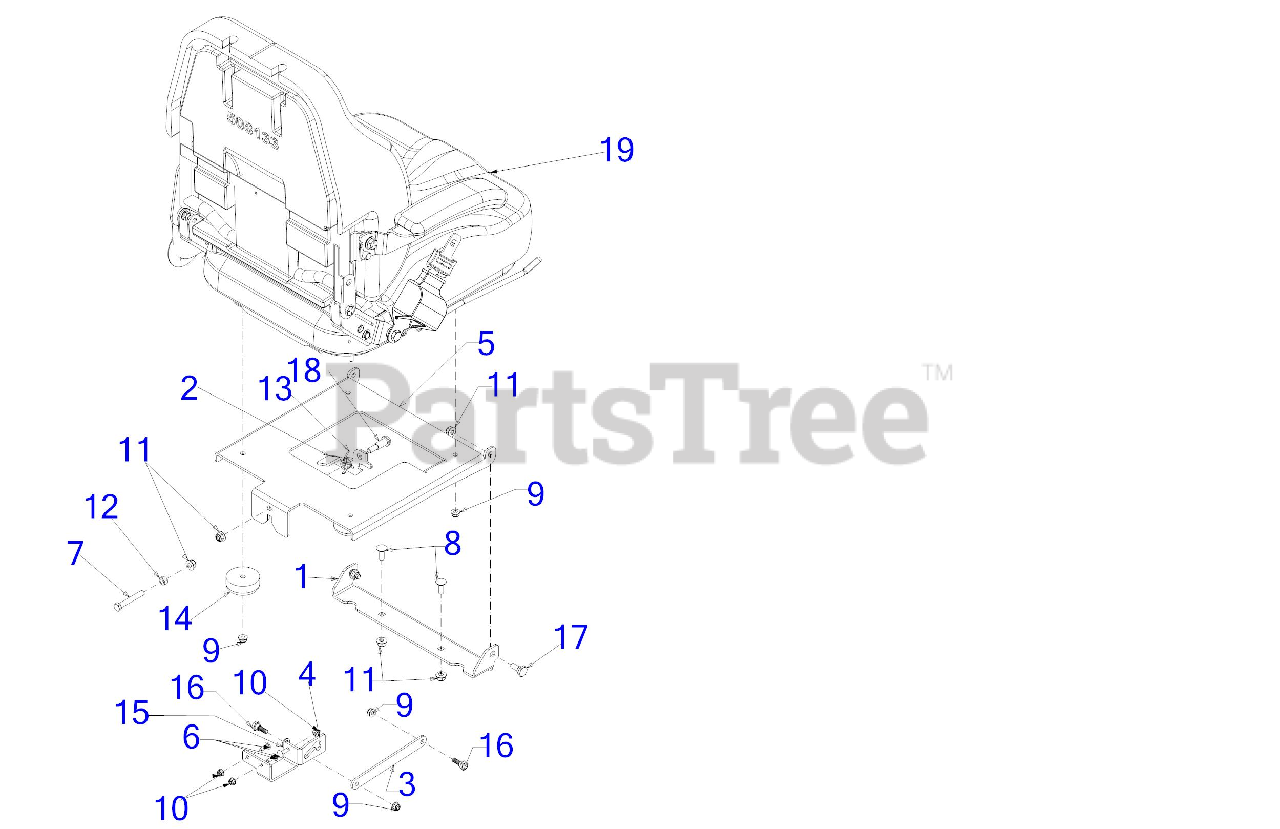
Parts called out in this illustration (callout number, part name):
3	SEAT LOCKOUT BRACKET
4	SEAT LOCKOUT MOUNT
6	SCREW 1/4-20 x .75 GR5
7	HEX SCREW-3/8-16X2.5 GR5
8	CARRIAGE BOLT 3/8-16 x 1.00 GR5
9	FLANGE LOCK NUT 5/16-18
10	FLANGE LOCK NUT
12	HEX NUT
13	TORSION SPRING
14	RUBBER BUMPER
15	FLAT WASHER .469X.750X.054
16	SHOULDER SCREW .437 DIA x .265
17	SHOULDER SCREW
18	SHOULDER SCREW .50X.925
19	SEAT ASSEMBLY W/SUSPENSION
